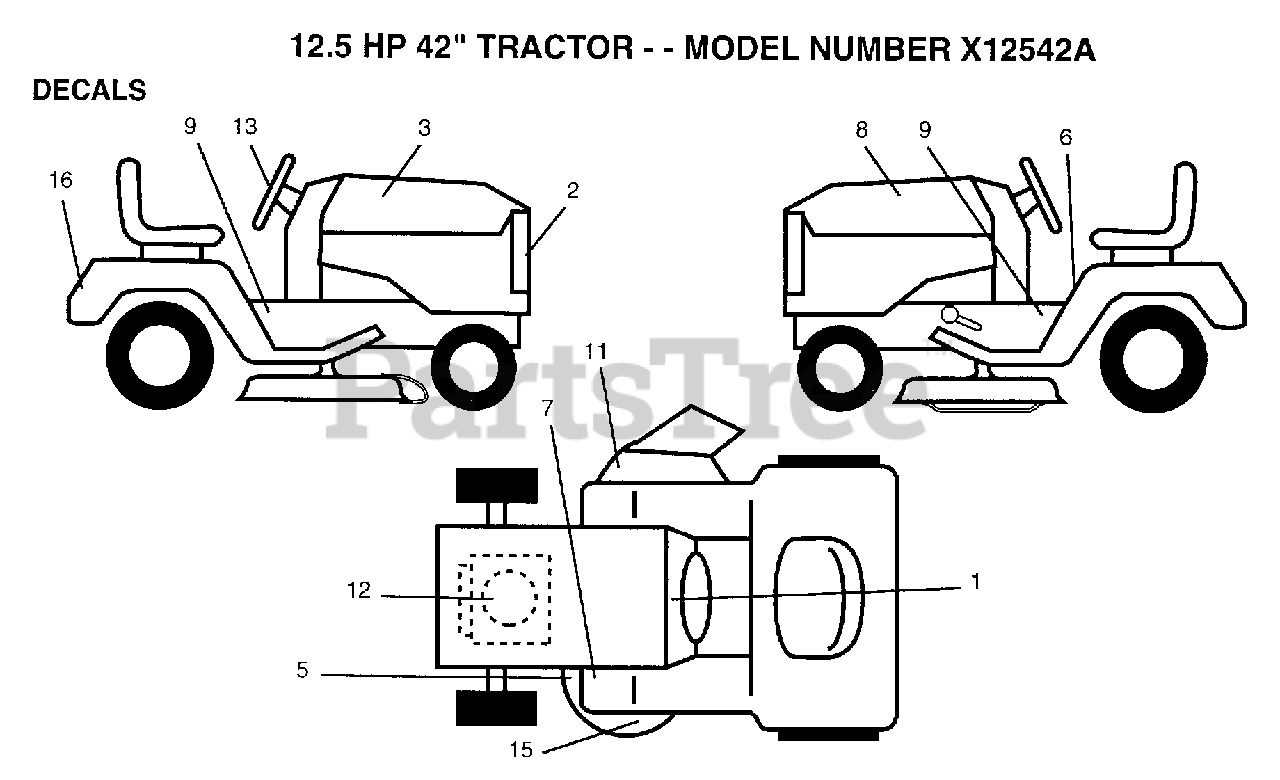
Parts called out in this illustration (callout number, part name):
2	DECAL, GRILL
3	"DECAL,HOOD RH "
5	DECAL
6	DECAL CAUTION
7	DECAL T
9	DECAL.CHASS.6SP
11	"DECAL, WARNING"
13	"DECAL,STR WHL "
16	"DECAL,LOGO"
